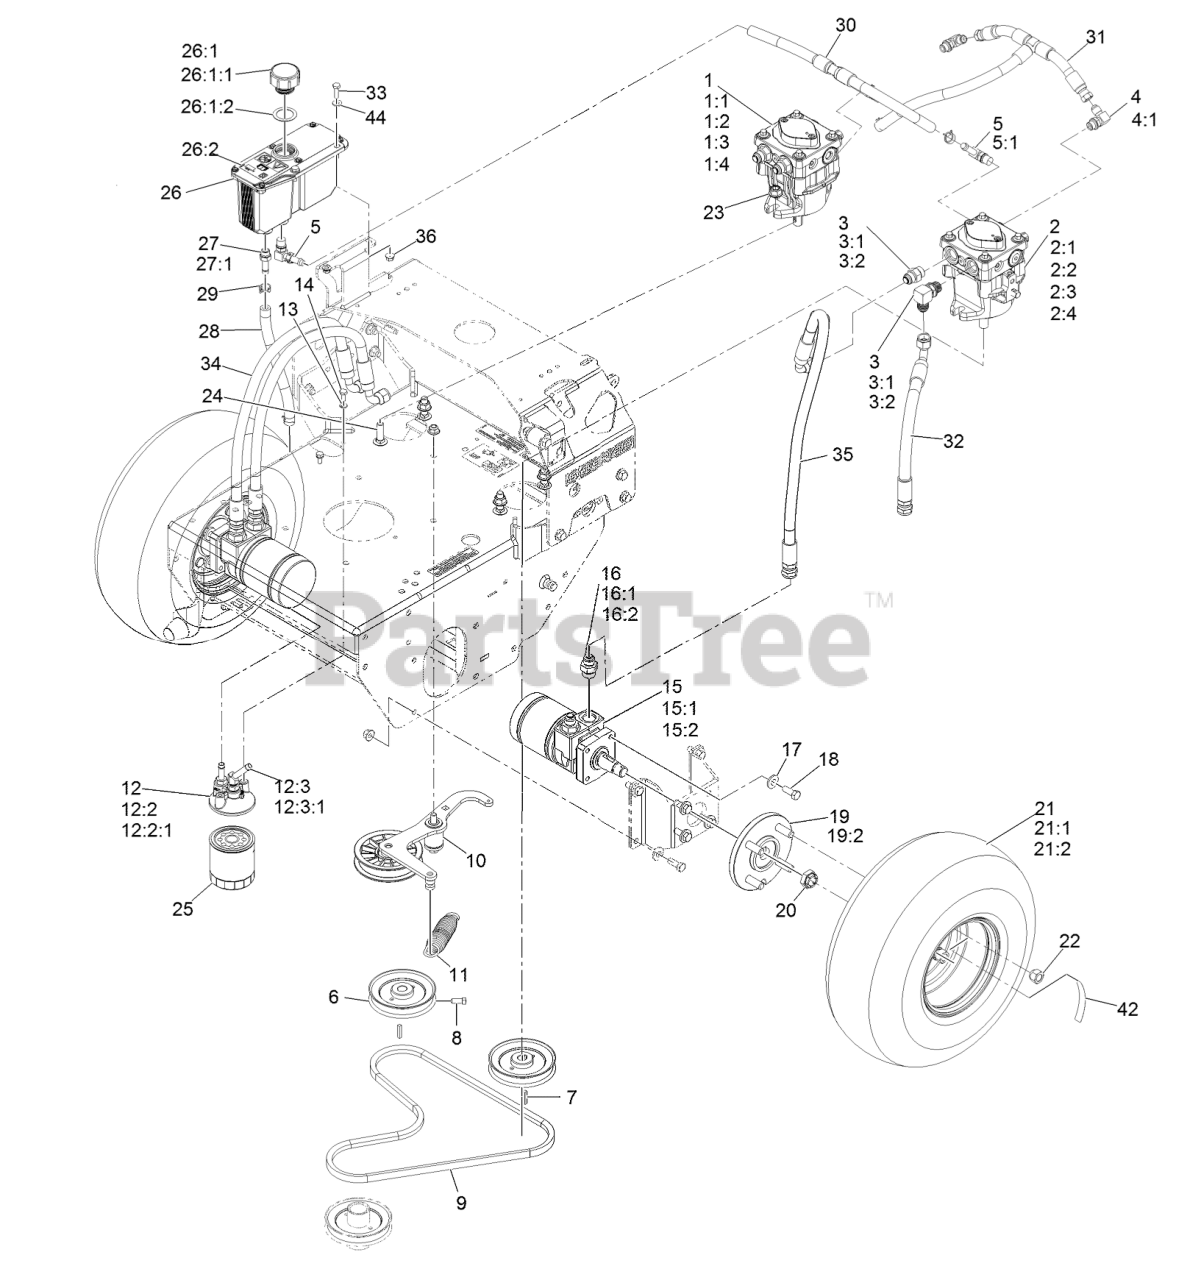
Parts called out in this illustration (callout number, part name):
1	RH HYD PUMP ASM
1:1	INPUT SHAFT KIT
1:2	BEARING-THRUST
1:3	CYLINDER BLOCK KIT
1:4	SEAL OVERHAUL KIT
2	LH HYD PUMP ASM
2:1	INPUT SHAFT KIT
2:2	BEARING-THRUST
2:3	CYLINDER BLOCK KIT
2:4	SEAL OVERHAUL KIT
3	FITTING-STRAIGHT
3	FITTING-90 DEG
4	FITTING-ELBOW, 90 DEG
4:1	O-RING
5	FITTING-ELBOW, 90
5:1	O-RING
6	SHEAVE ASM
8	SCREW-SET, SQH
9	BELT
10	ASM, PUMP IDLER
11	SPRING-EXTENSION
12	ASM, FILTER HEAD
12:2	ADAPTER-STRAIGHT
12:2:1	O-RING
12:3	FITTING-BARBED, 45 DEG
12:3:1	O-RING
13	WASHER-LOCK
14	SCREW-HH
15	HYD MOTOR ASM
15:1	SEAL KIT
15:2	BEARING AND SEAL KIT
16	FITTING-STRAIGHT
16:1	O-RING
17	WASHER-BELLEVILLE
18	SCREW-HH
19	WHEEL HUB ASM
19:2	STUD-WHEEL
20	NUT-LOCK
21	WHEEL AND TIRE ASM
21:1	TIRE-TURFMASTER
21:2	RIM-WHEEL
22	NUT-LUG
23	NUT-HF, NI
24	BOLT-CARR
25	FILTER-25 MICRON, BI-DIRE
26:1	Reservoir-HYD
26:1:1	Cap-Reservoir, HYD
26:1:2	GASKET-CAP
26:2	DECAL-WARNING
27	ADAPTER-STRAIGHT
27:1	O-RING
28	HOSE-CHARGE
29	CLAMP-HOSE
30	HOSE-CASE DRAIN
31	HOSE-CHARGE
32	ASM, HP HOSE
33	SCREW-HH
34	HYD HOSE ASM
35	HYD HOSE ASM
36	NUT-HHF
42	DECAL-TORQUE WHEEL LUG-HU
44	WASHER-FLAT
